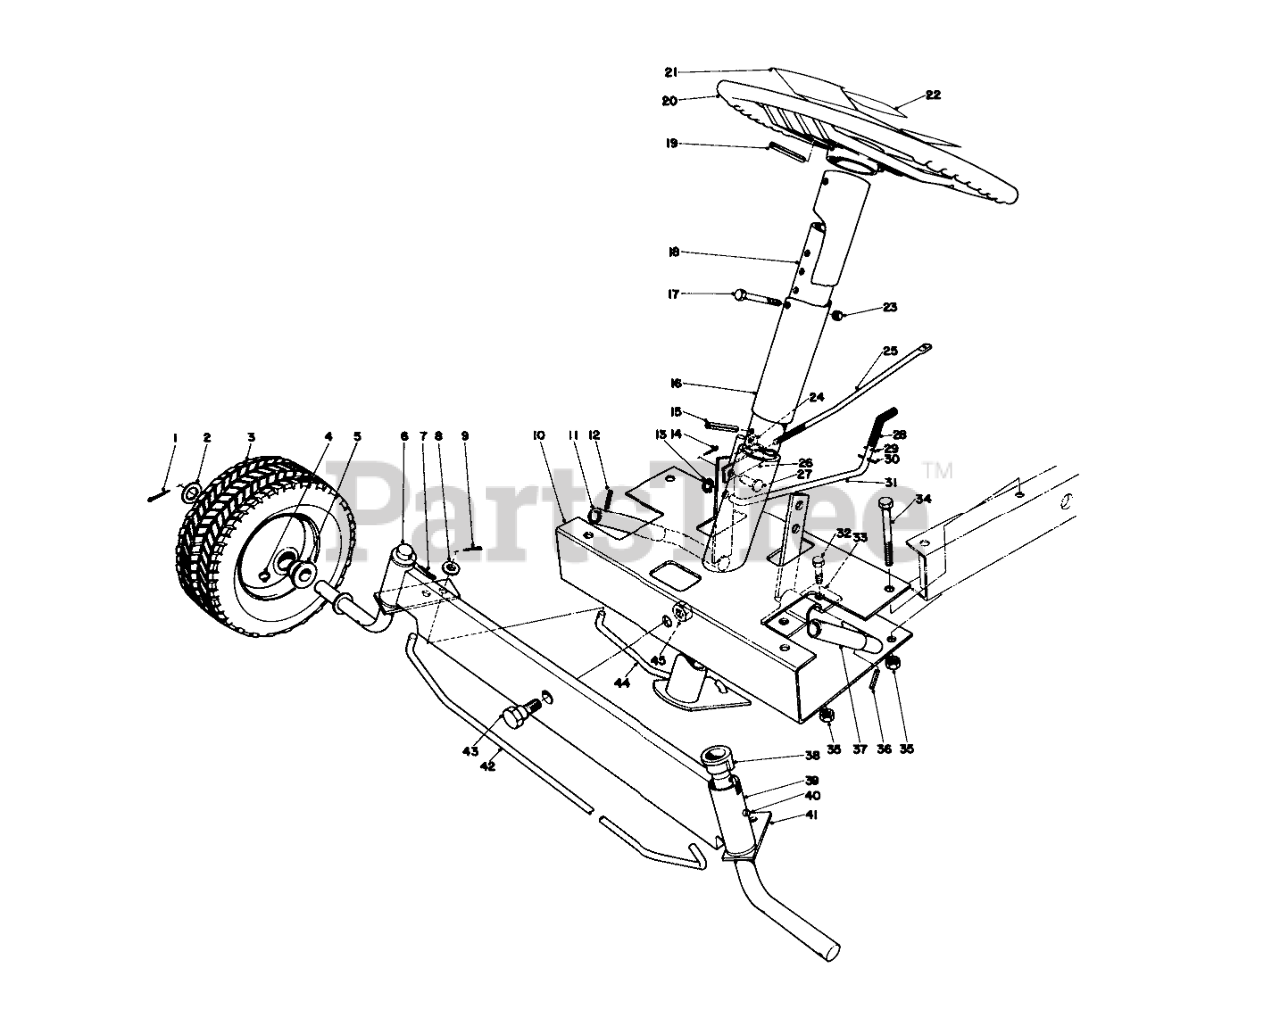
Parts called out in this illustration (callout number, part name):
1	PIN-COTTER
2	WASHER-FLAT
3	Wheel
4	FITTING-GREASE
5	BUSHING
6	Spindle R.H.
7	PIN-COTTER
8	WASHER-FLAT
9	PIN-COTTER
10	Front Frame
11	Brake Pedal
12	Pin-Roll
13	RING-GRIP
14	PIN-COTTER
15	Coil Pin
16	Steering Tube Outer
17	SCREW-HH
18	Tube Steering
19	PIN-ROLL
20	Steering Wheel
21	Decal
22	Decal
23	NUT-LOCK, CONE
24	NUT-SQUARE
25	Rod-Brake
26	Clevis Brake
27	PIN-CLEVIS
29	PIN-ROLL
30	PIN-ROLL
31	Rod-Parking Brake
32	SCREW-HH
33	Bracket-Clutch & Brake
34	SCREW-HH
35	NUT-LOCK, CONE
36	PIN-ROLL
37	Clutch Pedal
38	Bushing
39	Front Axle
40	GREASE FITTING
41	Spindle L.H.
42	Tie Rod
43	Shoulder Bolt
44	Rod Steering
45	1/2-13 CONELOCK NUT
